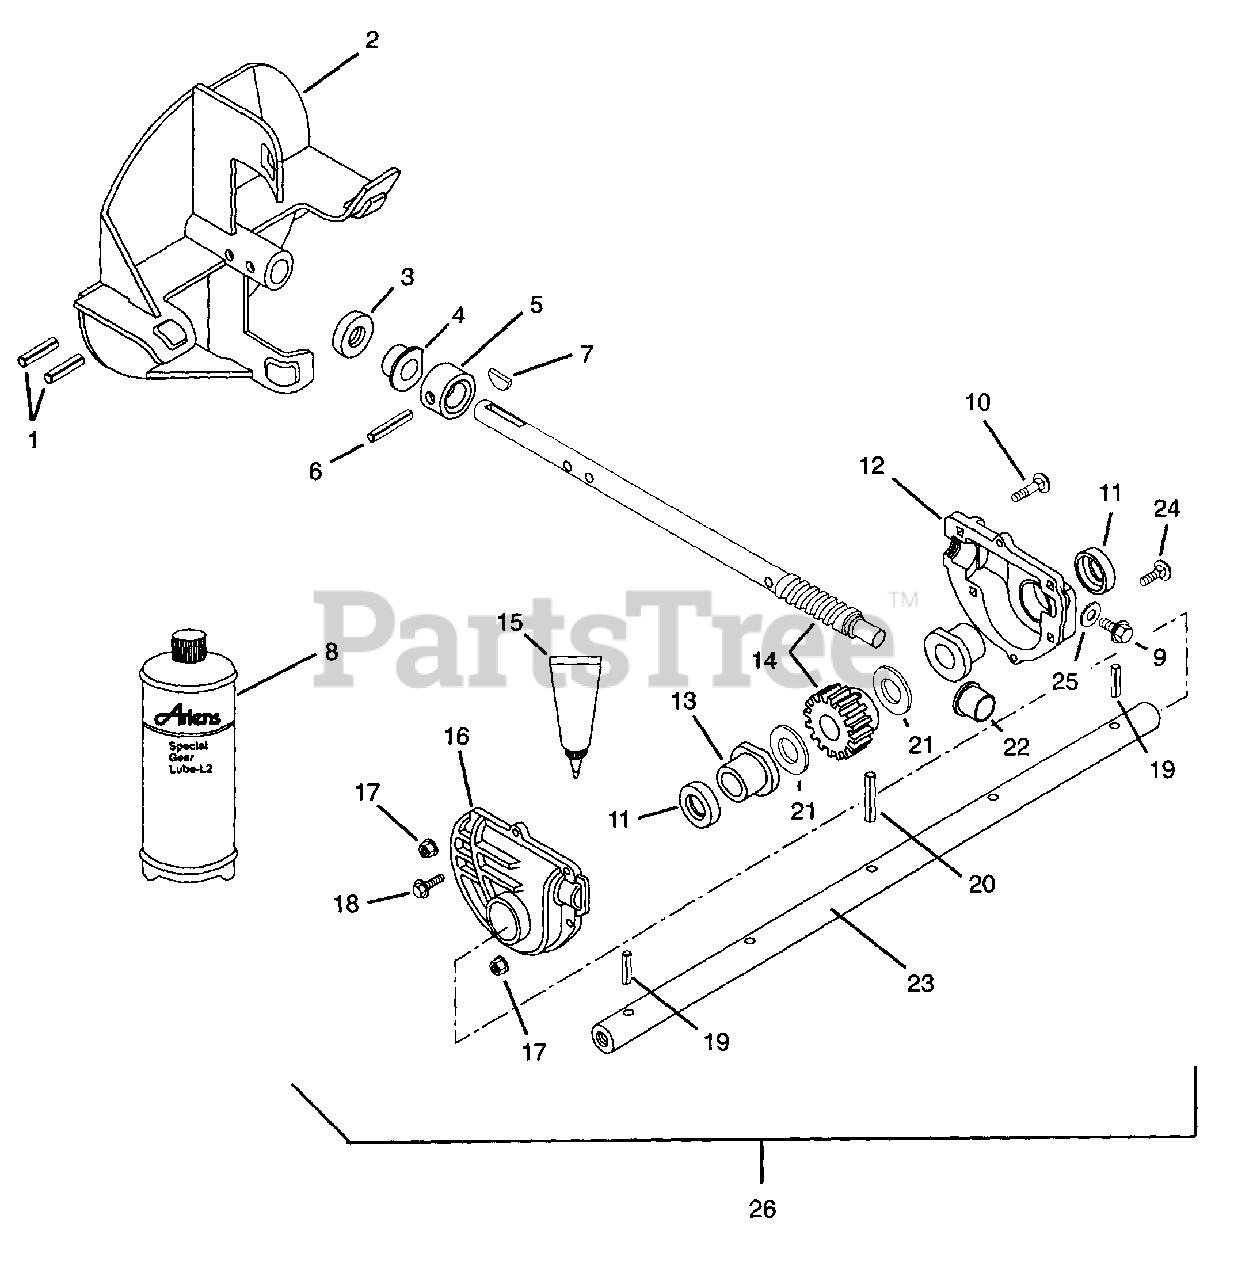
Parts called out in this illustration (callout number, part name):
1	PIN-ROLL .250X1.75
2	FAN - 12"
3	SEAL-OIL .750X1.375X.250
4	BSHG-FLG .750X1.000X.750X1.250
5	THRUST COLLAR
6	PIN-GRV .188X1.25 TP A
7	KEY-WDRF .188X.875X.375 SAE11
8	ARIENS 16 OZ.BOTTLE OF L2 LUBE
9	@SCR-TAP .38-16X.50 HWH TR YWZ
10	@BLT-RDHDSQNK .25-20X1.25 G5YZ
11	SEAL-OIL 1.000X1.375X.250
12	CASE, GEAR-LH-LARGE BORE-ALUM.
13	BSHG-FLG 1.00X1.12
14	WORM SHAFT & GEAR ASSY
15	LOCTITE GASKET 518--850CC CRTG
16	CASE, GEAR-RH-LARGE BORE-ALUM.
17	@NUT-SPNLK-FLG .25-20 YWZC
18	SCR-TAP 10-24X.75 HWH TR YWZC
19	PIN-ROLL .188X1.50
20	PIN-GRV .313X1.44 TP C
21	WSHR-HRD-THRS 1.007X1.542X.062
22	BSHG-FLG .502X1X.750
23	SHAFT, RAKE - 24"
24	BLT-RDHDSQSHK .25-20X.88 GR5YW
25	WSHR-FIBER .437X.656X.032
26	GEAR CASE-LRG BORE-ALUM.- 24"
